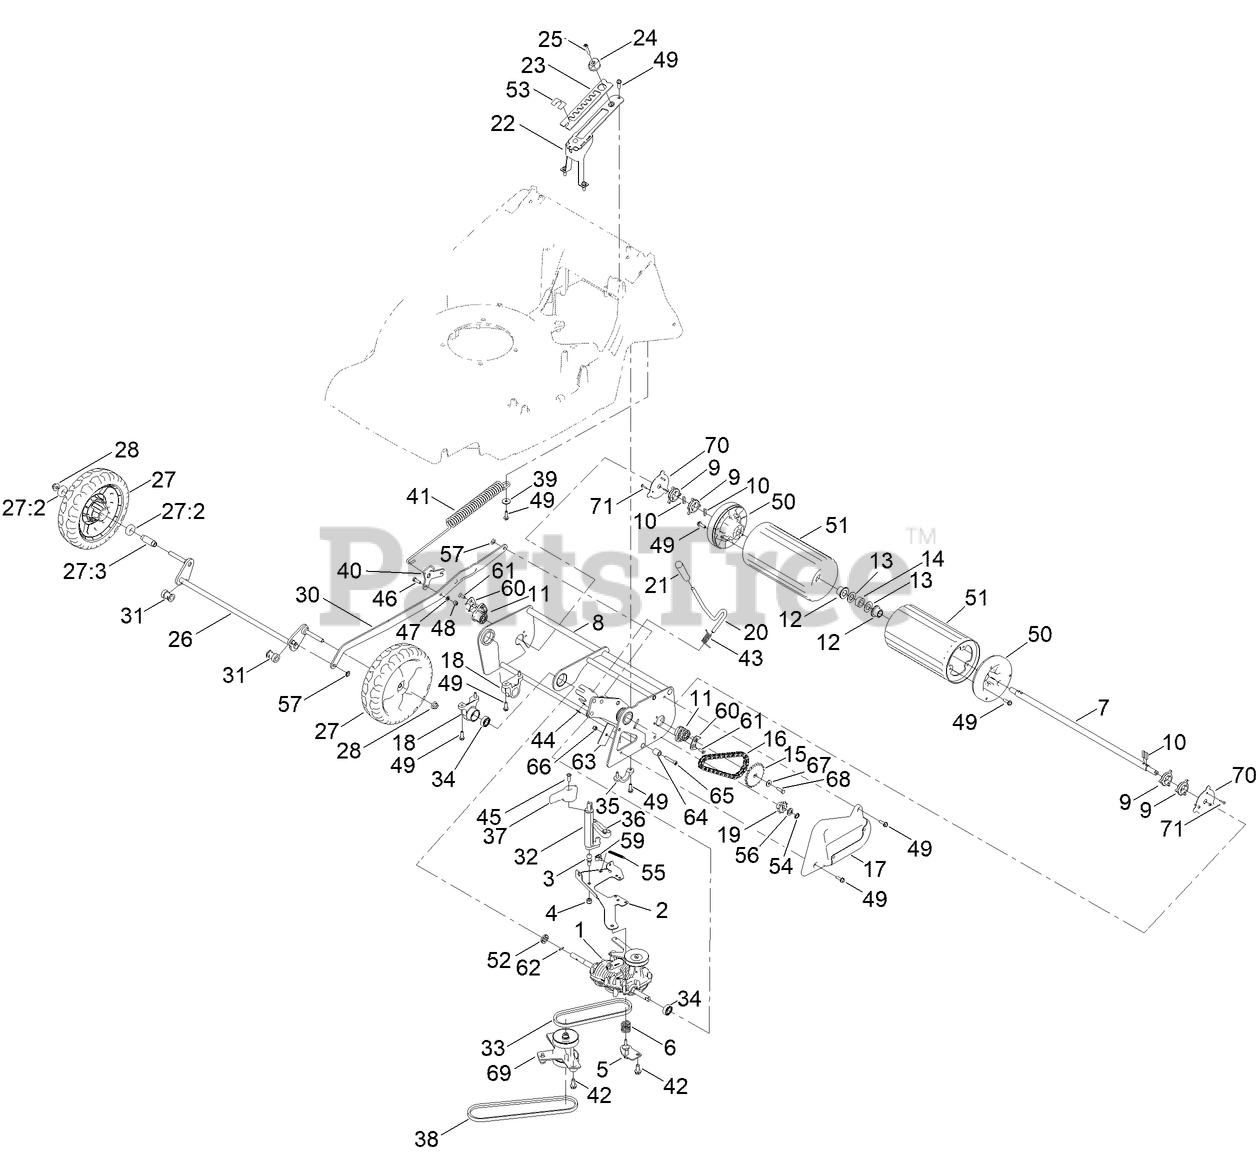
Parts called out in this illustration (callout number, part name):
1	MG510 3-SPEED GEARBOX
2	GEARBOX MOUNTING PLATE
3	STUD-BALL
4	NUT-HEX, NI
5	GEARBOX BRACKET ASSEMBLY
6	SPRING-MOUNTING, GEARBOX
7	SHAFT-ROLLER, PRO
8	REAR FRAME, 56 (PRO)
9	CAM-DRIVE
10	KEY-DRIVE
11	BUSH, REAR ROLLER
12	BUSHING-ROLLER, OILITE
13	WASHER
14	SPACER-ROLLER
15	SPROCKET
16	CHAIN(46 PITCHES 3/8")
17	CHAIN COVER ASM
18	MOUNT-BEARING, FRAME (REAR)
19	SPROCKET, 10T
20	LEVER-HOC
21	KNOB-HOC
22	HOC TOWER ASSEMBLY
23	PLATE-HOC
24	ADJUSTER-HOC
25	SCREW-HSH
26	56 FRONT AXLE ASSEMBLY HD
27:2	BEARING-BALL
27:3	SPACER
28	NUT-HF, NI
30	CONNECTING ROD ASSEMBLY
31	BEARING-AXLE, FRONT
32	ROD-SELECTOR, 3 SPEED
33	V-BELT
34	BEARING, BALL 12MM
35	AXLE- SUPPORT, REAR
36	ARM-SELECTOR, 3 SPEED
37	KNOB- SELECTOR, 3 SPEED
38	V-BELT
39	WASHER
40	SPRING LOAD LEVER
41	SPRING COUNTER BALANCE
42	SCREW-HWH
43	SPRING-TORSION, HOC
44	GRIP-FIX
45	SCREW
46	SCREW-HH
47	WASHER-PLAIN
48	NUT-NYLOC
49	SCREW-TAPTITE
50	CAP-ROLLER, END
51	ROLLER SHELL ASSEMBLY
52	RETAINING COLLAR, DRIVE SHAFT
53	DECAL-HOC
54	CIRCLIP-EXTERNAL, HD
55	LEVER-SPRING, CLUTCH (RETURN)
56	WASHER-THRUST
57	WASHER-STARLOCK
59	CLIP-CONDUIT, TWIN
60	BEARING SUPPORT PLATE
61	SCREW-TAPTITE
62	PIN, ROLL, 3MM X 16MM
63	BACK PLATE, TENSIONER
64	PULLEY, TENSIONER
66	NUT-NYLOC
67	WASHER-PLAIN
68	SCREW-HH LOCK
69	JACK SHAFT ASSEMBLY
70	COVER, BEARING
